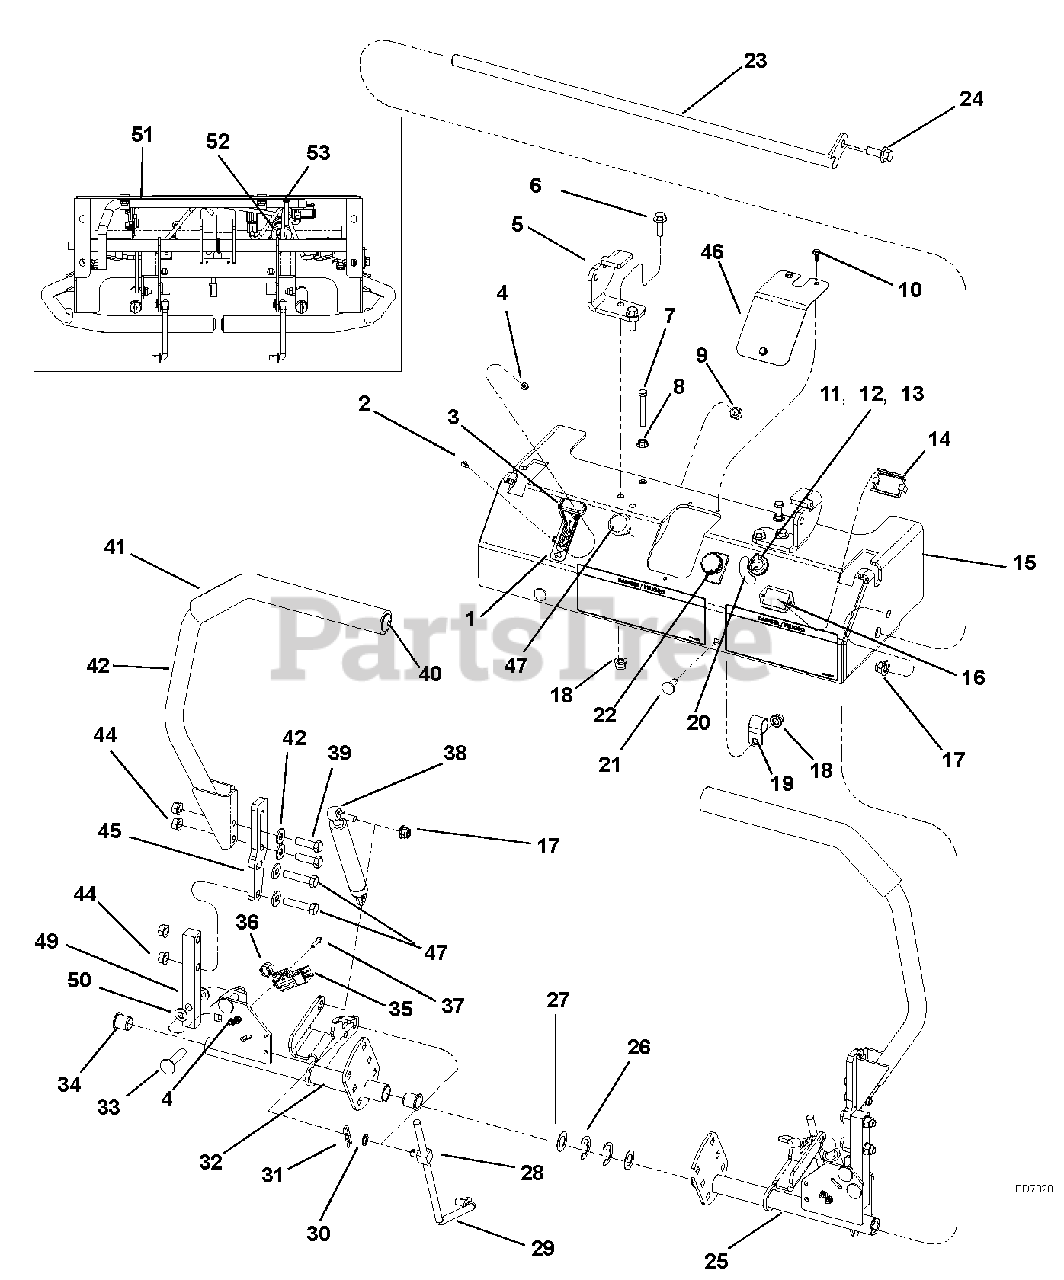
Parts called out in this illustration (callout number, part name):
1	DECAL, CONSOLE
2	SCREW,.164 X .500 ZN RD HD MACH
3	THROTTLE
4	NUT, 8-32 ELASTIC STOP
5	BRACKET, LH, SEAT PLATE
6	SCREW, HEX, FL, JDS123, M8 X 1.25 X 25
7	BOLT, 1/4-20 X 2.00 HEX 5 Y
8	SPINLOCK NUT - 1/4
9	NUT, .375 UNF2B HEX JDS14 8 ZN
10	SCREW, TAP 10-24 X .50 HEX WASHER HEAD
10	3
11	KEY, IGNITION A880
12	NUT, KNURLED
13	SWITCH, IGNITION KEY
14	CLIP, ZTRAK HOURMETER RETAINING
15	WLDT, CONSOLE
16	METER, HOUR - LCD
17	LOCKNUT, FL, ISO7043, M10 X 1.5-10
18	LOCKNUT, FL, ISO7043, M8 X 1.25
19	P-CLIP, .750 INSULATED
20	LABEL, IGNITION KEY
21	BOLT, M8X1.25X20 CRG 8.8 Y
22	SWITCH, PTO (PULL/PUSH)
23	PIVOT, CONTROL SHAFT - PLATED
24	SCREW, HEX M10X1.5X25
25	WLDT, PIVOT CONTROL LH
26	RING, RETAINING
27	WASHER, .627 X 1.09 X .030 THST Y
28	SWIVEL, 3/8-24
29	ROD, CONTROL
30	SHIM, CIRCULAR
31	PIN, HAIR .094 X 1.53 5/16-1/2 Y
32	WLDT, PIVOT CONTROL RH
33	BOLT, RH, SQNECK, JDS137, M10 X 1.5
34	BUSHING, NYLON
35	SWITCH, PLUNGER DP - N.O. - N.C.
35	2
36	LOCKNUT,DIN6924,M10X1.5-10-ZN
37	SCREW, 8-32X .75 PAN PHL Y
38	ABSORBER, ASM. WITH BALL STUD
39	BOLT, 3/8-16 X 1.25 HEX 5 Y
39	4
40	PLUG, 7/8" END
41	GRIP, FOAM
42	WLDT, CONTROL LEVER
43	8
43	WASHER, .313 REG FLAT Y
44	8
44	LOCKNUT, 3/8-16 WHIZ Y
45	PLATE, LEVER ADJ.
46	COVER, CONSOLE
47	CABLE, CHOKE
48	4
48	BOLT, 3/8-16 X 1.75 HEX 5 Y
49	ARM, CONTROL
50	WASHER, FLAT NYLON .375 X .75 X .060 REV
51	WIRING HARNESS
52	WASHER, M21 X 37 X 3 DIN 125T2 300HV Y
53	CABLE TIE, .31 X 14.6 - BLACK
